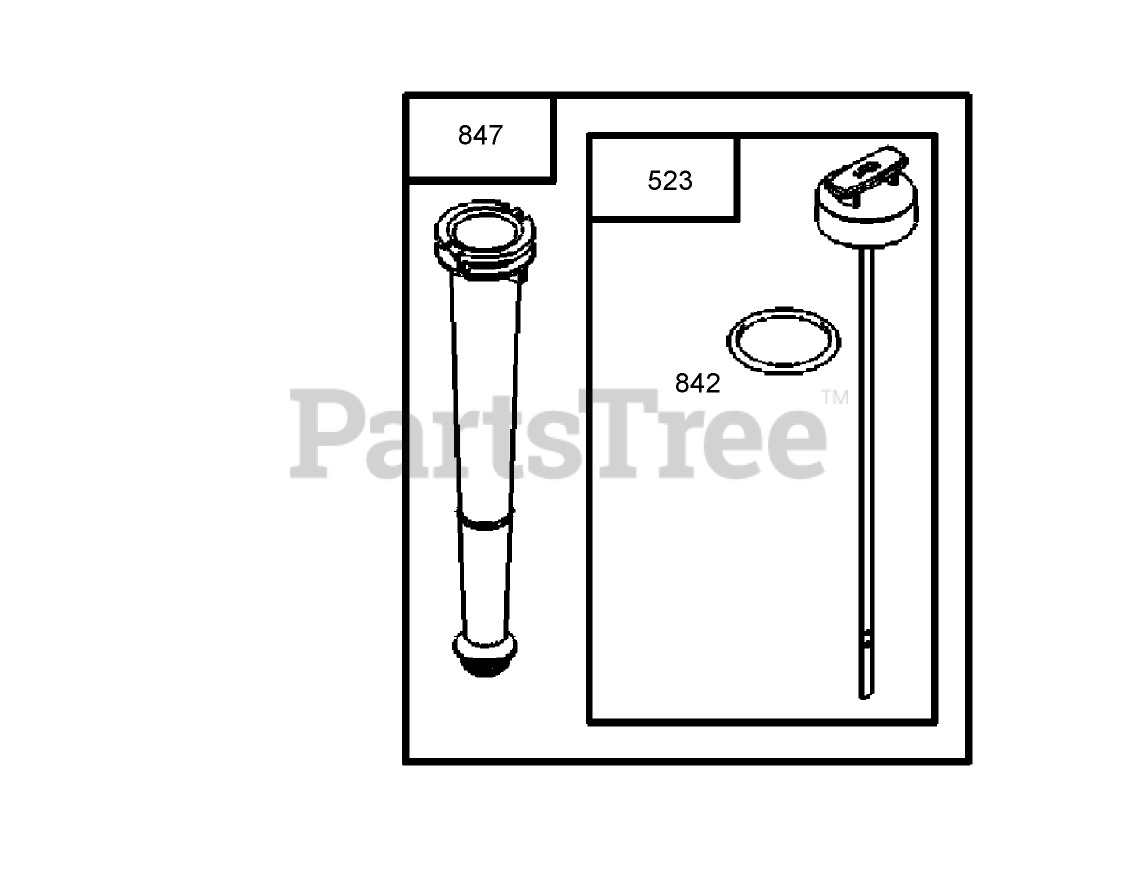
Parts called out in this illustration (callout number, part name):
523	Dipstick
842	Seal-O Ring
847	Dipstick and Tube ASM
